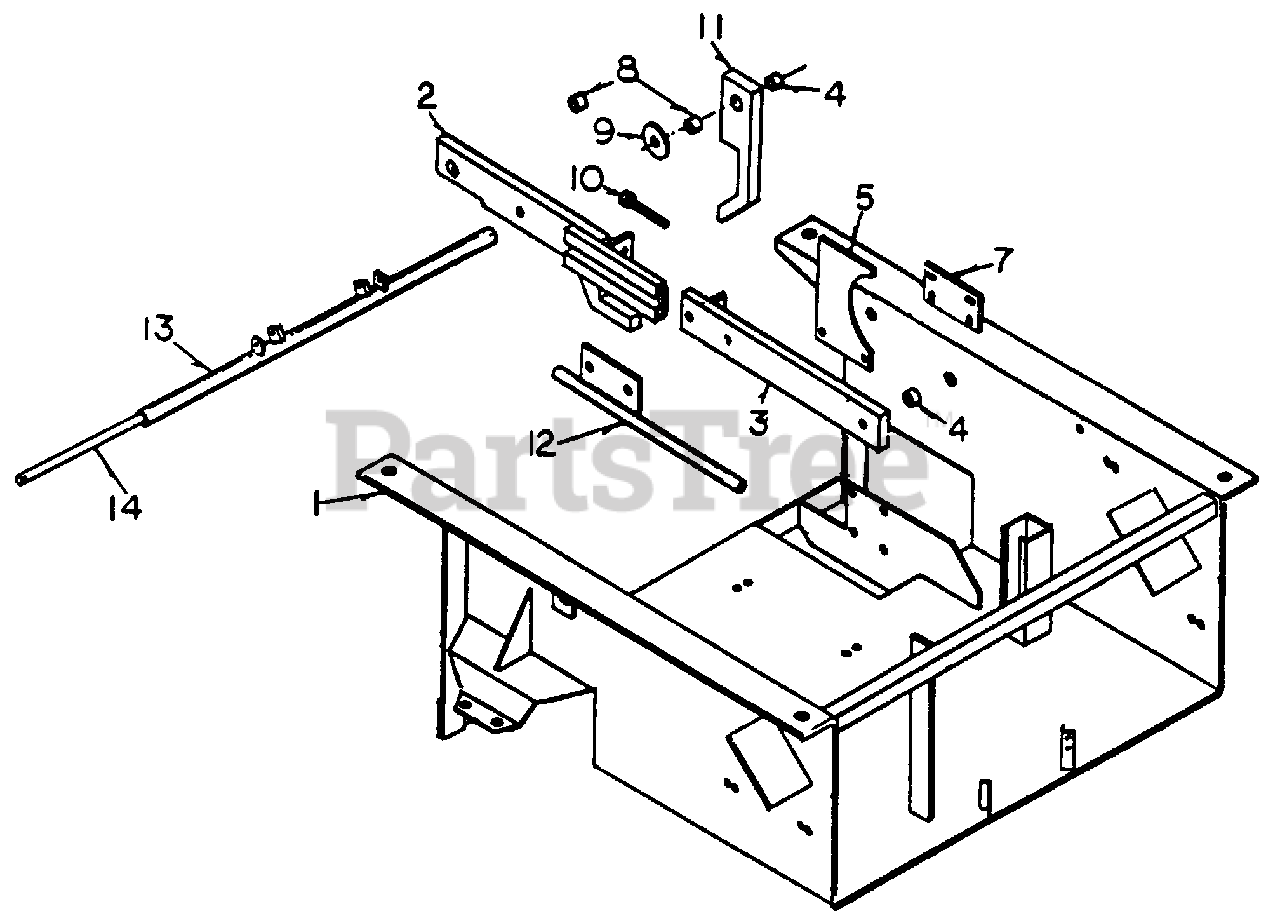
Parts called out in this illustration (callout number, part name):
1	Base
2	RH Deck Lift Arm, Front RH
3	Deck Lift Arm, Back
4	Bushlng, Short
5	Belt Retainer
7	Belt Retainer Mount
8	Bushing, Long
10	Deck Belt Adjustment Bolt
11	Forward Nose Down Lock
14	Crss Bar Pin
